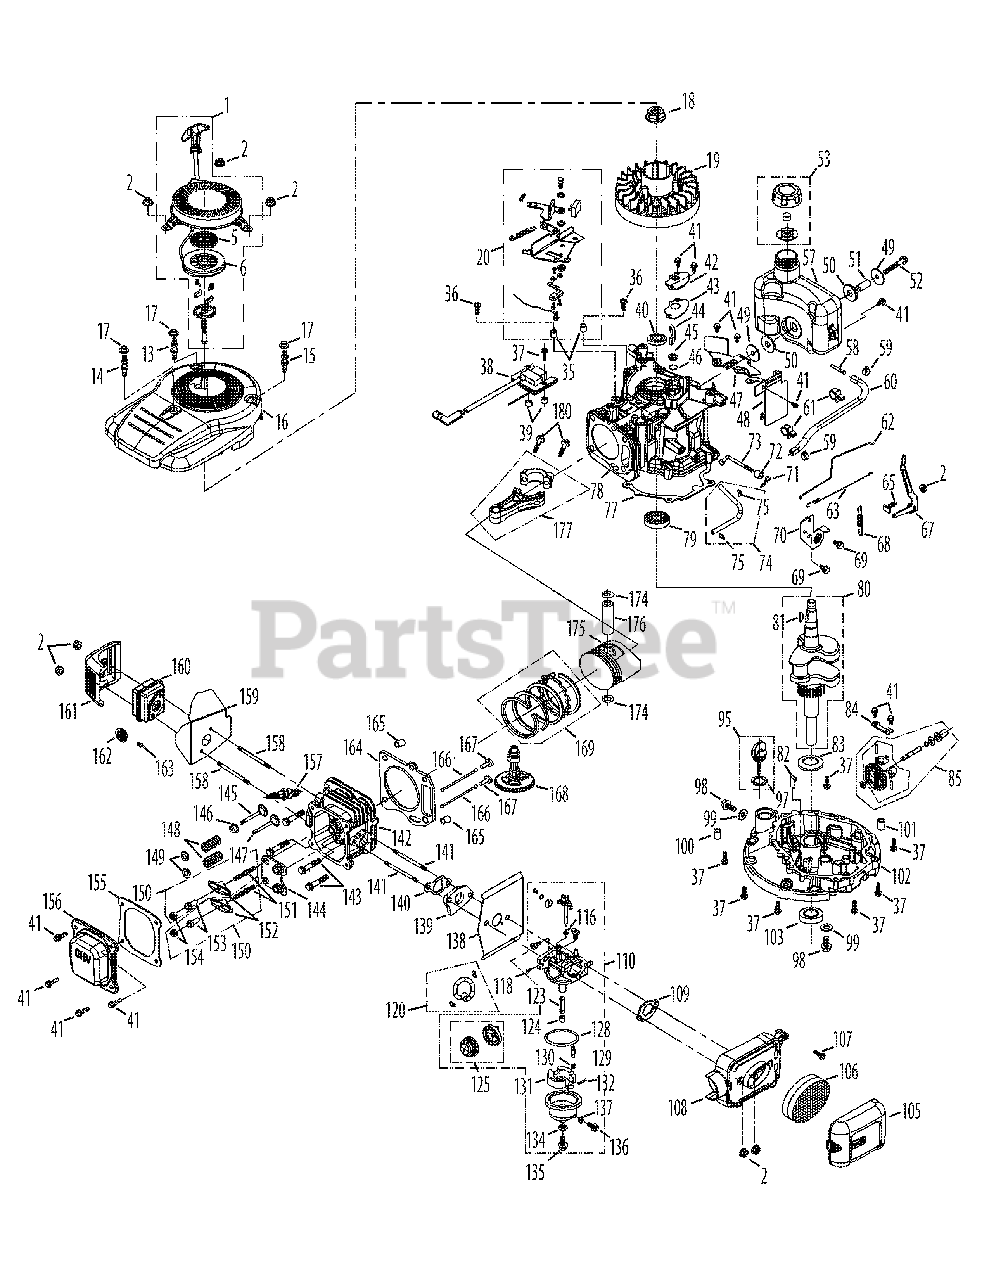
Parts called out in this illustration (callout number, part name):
1	Recoil Starter Assembly
2	Nut M6 X 10 Mm
5	Spring
6	Pulley
13	Starter/Shroud Stud Black M6 x 75
14	Starter/Shroud Stud Front M6 x 75.3
15	Starter/Shroud Stud White M6-73
16	Engine Shroud (M0)
17	Engine Shroud Spacer
18	Flywheel Nut M14
19	Flywheel
20	Brake Assembly
35	Brake Spacer
36	Brake Assy Bolt M6×35
37	Bolt M6x28
37	Bolt M6×28
38	Ignition Coil Assembly
39	Ignition Coil Spacer
40	Upper Crankshaft Seal
41	Bolt M6×14
42	Breather Cover Plate
43	Breather Gasket
44	Breather Screen
45	Breather Spring
46	Breather Valve
47	Fuel Tank Bottom Bracket
48	Tank/Label Bracket
49	Fuel Tank Washer
50	Rubber Bushing
51	Fuel Tank Bushing
52	Tank Bolt M8x50
53	Fuel Cap Assembly
57	Fuel Tank Assembly
58	Fuel Filter
59	Fuel Hose Clamp
60	Fuel Hose
61	Plastic Support Clamp
62	Throttle Linkage
63	Throttle Linkage Spring
65	Governor Arm Bolt
67	Governor Arm
68	Governor Spring
69	Bolt M6×12
70	Throttle/Governor Bracket
71	Governor Cotter Pin
72	Governor Seal
73	Governor Arm Shaft
74	Breather Hose Assembly
75	Breather Hose Clamp
77	Crankcase Cover Gasket
78	Crankcase
79	Main Bearing
80	Crankshaft Assembly
81	Woodruff Key
82	Oil Return Seal
83	Crankshaft Thrust Washer
84	Governor Gear Mounting Plate
85	Governor Gear/Shaft Assembly
95	Dipstick Assembly
97	Dipstick O-Ring
98	Oil Drain Plug
99	Oil Drain Plug Washer
100	Crankcase Cover Dowel 9x14
101	Crankcase Cover Dowel 7x14
102	Crankcase Cover
103	Lower Crankshaft Seal
105	Outer Air Filter Cover
106	Air Filter Element, Oval
107	A/F Base Bolt M6×30
108	Inner Air Filter Housing
109	Carburetor Gasket Plate
110	Carburetor Assembly
116	Fiber O-Ring
118	Idle Speed Adjusting Screw
120	Primer Hose Assembly
123	Main Nozzle (Emulsion Tube)
124	Main Jet
125	Primer Assembly
128	Fuel Bowl O-Ring
129	Needle Valve
130	Needle Valve Spring
131	Float
132	Float Pin
134	Fuel Bowl Gasket
135	Fuel Bowl Mounting Bolt
136	Fuel Drain Plug
137	Fuel Drain Plug Gasket
138	Carburetor Gasket
139	Carburetor Insulator
140	Carburetor Insulator Gasket
141	Carb Stud M6x92
142	Cylinder Head
143	Head Bolt M8×54
144	Push Rod Guide
145	Intake Valve
146	Intake Valve Seal
147	Exhaust Valve
148	Valve Spring
149	Valve Spring Retainer
150	Rocker Arm Assembly
151	Rocker Arm Stud
152	Rocker Arm
153	Fulcrum Nut
154	Jam Nut
155	Valve Cover Gasket
156	Valve Cover
157	Spark Plug/F6rtc
158	Muffler Stud M6x95
158	Muffler Stud
159	Muffler Gasket
160	Muffler Assembly
161	Muffler Shield
162	Spark Arrestor
163	Spark Arrestor Screw
164	Cylinder Head Gasket
165	Cylinder Head Dowel 10x16
166	Push Rod (2 per order)
167	Tappet
168	Camshaft Assembly
169	Piston Ring Set
174	Piston Pin Snap Ring
175	Piston
176	Piston Pin
177	Connecting Rod Assembly
180	Connecting Rod Bolt
